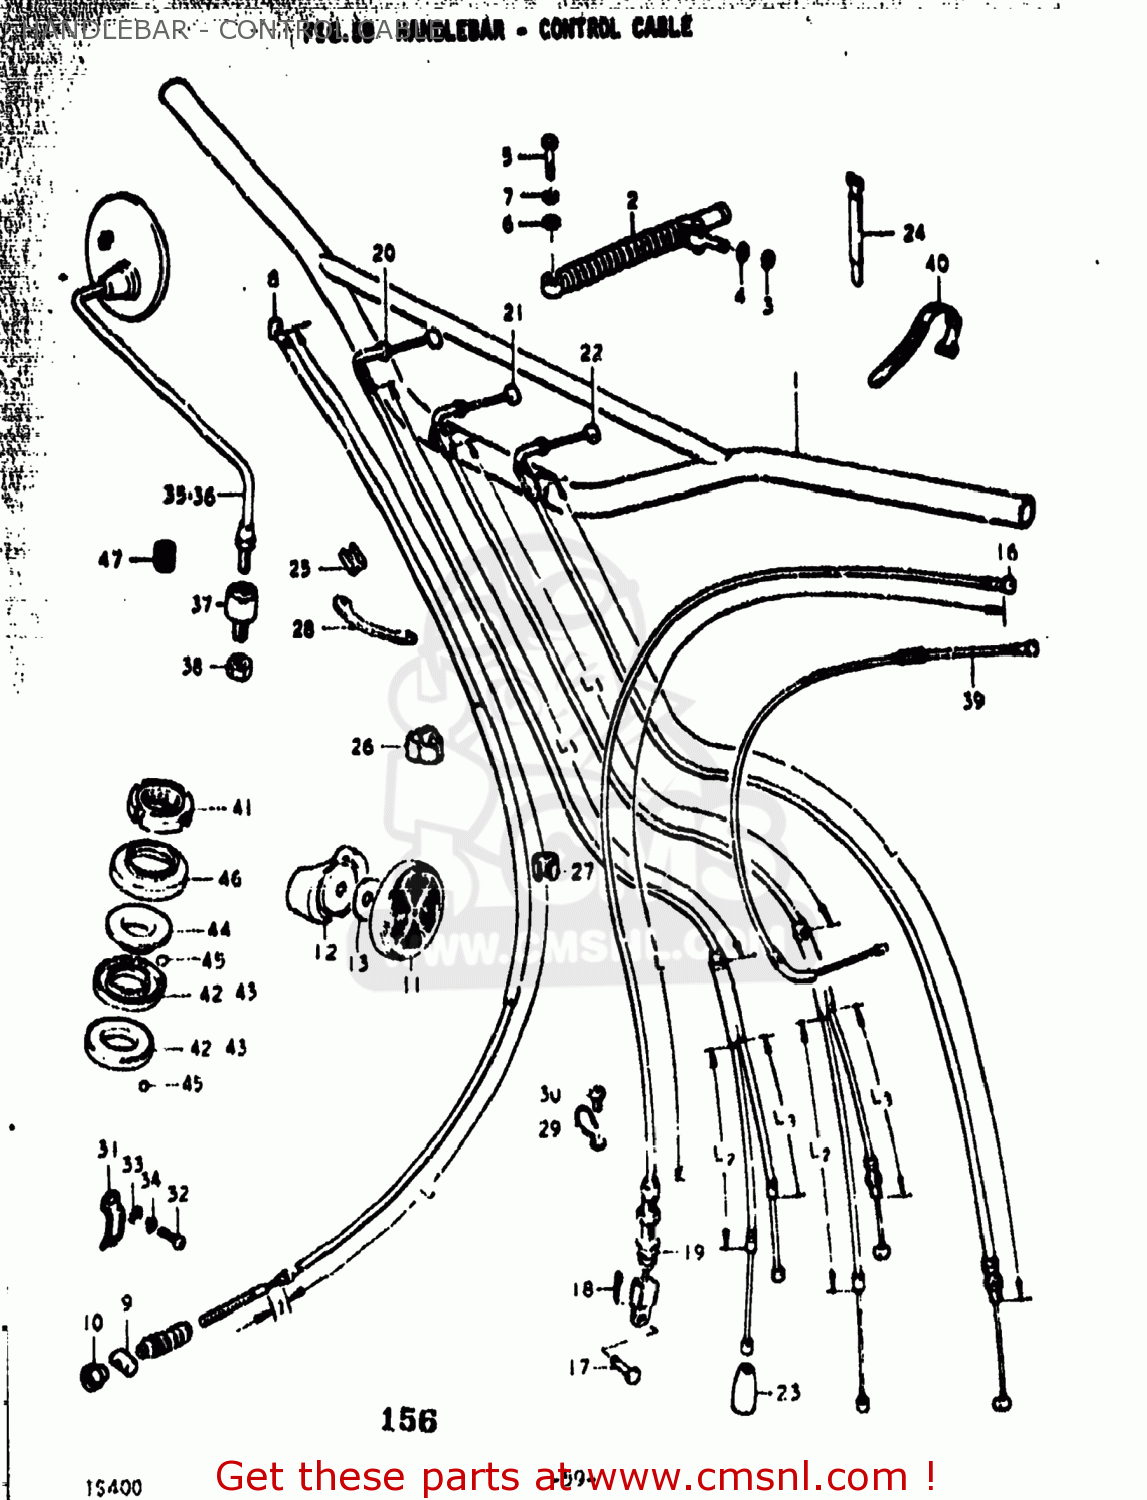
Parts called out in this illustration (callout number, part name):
1	HANDLEBAR
2	DAMPER ASSY, HANDLE
3	E RING 6MM
4	WASHER
5	BOLT
6	WASHER
7	LOCK WASHER
8	CABLE,FRONT BRAKE
9	PIN
10	NUT
11	REFLEX REFLECTOR,FR
12	SPACER
13	WASHER (6.5X20X1.2)
14	WASHER
15	LOCK WASHER
16	CABLE ASSEMBLY,CLUTCH
17	PIN(L:15)
18	PIN
19	SEAL,DUST(10X17X45)
20	CABLE ASSEMBLY,THROTTLE
21	CABLE ASSEMBLY,THROTTLE
22	CABLE ASSEMBLY,THROTTLE
23	SEAL,DUST(7X18X30)
24	CLAMP
25	CLIP
26	CLAMP
27	CLIP
28	GUIDE,CABLE
29	GUIDE,WIRING HARNESS
30	SCREW 6X12
31	CLAMP
32	SCREW 6X12
33	WASHER
34	LOCK WASHER
35	MIRROR ASSEMBLY,RIGHT
36	MIRROR ASSEMBLY,LEFT
37	RUBBER
38	NUT
39	CABLE ASSEMBLY,DECOMPRESSION
40	CLAMP(L:120)
41	NUT,STEERING STEM(25X44X10)
42	RACE,STEERING,INNER,UPPER
43	LACE,STEERING INNER LWR
44	LACE,STEERING OUTER UPR
45	BALL
46	DUST SEAL,STEERING UPR
